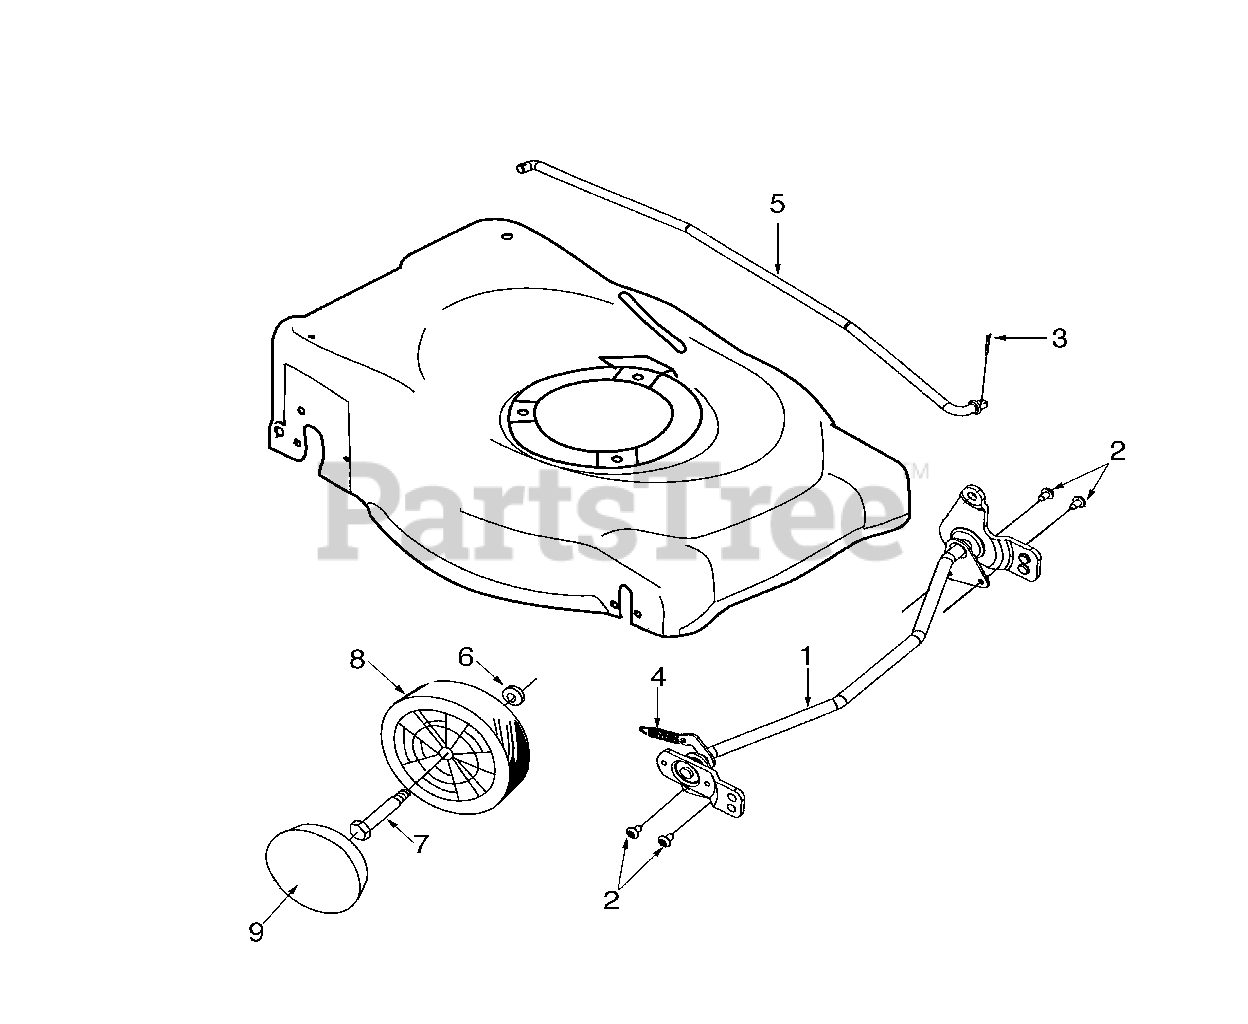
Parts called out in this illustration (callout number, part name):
1	Axle Ass'y, Frt.
2	AB Pan Scr. 1/4-14 x .50 Lg.
3	Cotter Pin .072 x 1.12 Lg.
4	Ext. Spring
6	Spr. Washer
7	Shl. Bolt .498 x 1.445 3/8-16
8	Wheel Ass'y - Complete Front
9	Hub Cap
